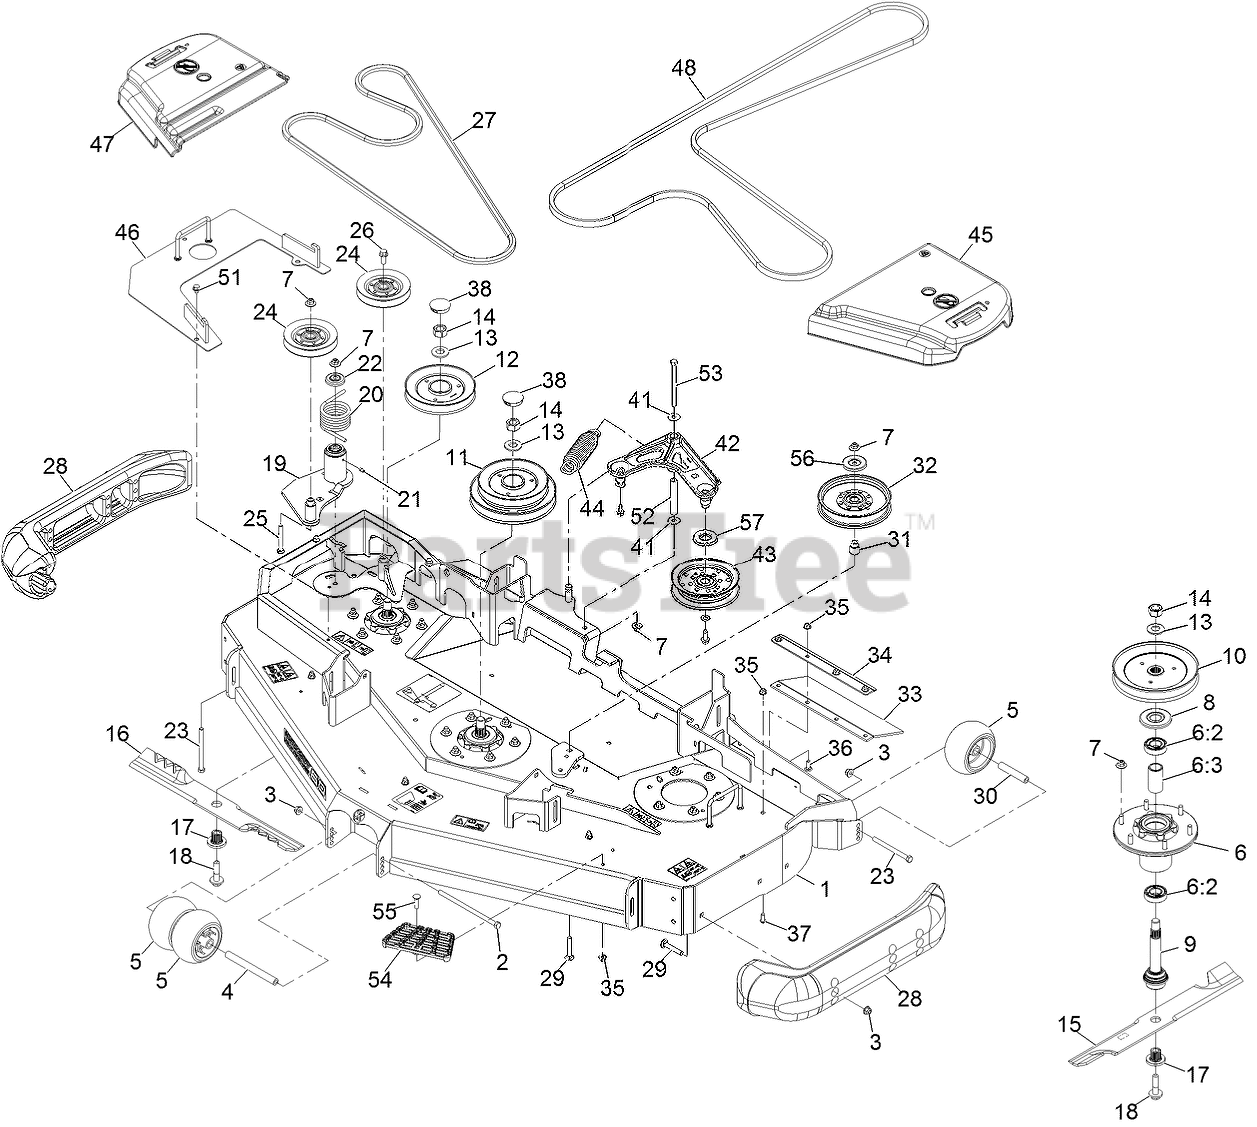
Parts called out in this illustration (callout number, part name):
1	ASM-DECK W/DECALS 60RD
2	SCREW-HH
3	NUT-HF, NI
4	SPACER-WHEEL
5	ROLLER-SCALP, ANTI
6	ASM-CUTTER HSG WITH BEARINGS
6:2	BEARING-BALL
6:3	SPACER-BEARING
7	Nut-Nyloc 3/8-16 Flg
8	GUARD,BEARING TOP .989
9	ASM-SPINDLE AND SEAL
10	SHEAVE,BLADE DRIVE 7.25
11	SHEAVE, DOUBLE 60RD
12	SHEAVE-RD REV DRIVE SERIES 4
14	NUT-HEX
15	Blade-Extreme 2, 20.50"
16	Blade-Low Lift 20.5, Rd60
16	Blade-Extreme 2-20.50, Rd60
17	BUSHING,SPLINED
18	SCREW,SEMS 1/2-20 X 2.19
19	IDLER ASM
20	SPRING-TORSION
21	FITTING-GREASE
22	GUARD-TOP
23	SCREW-HH
25	SCREW-HH
26	SCREW-HHF
27	BELT
28	SKID-BUMPER, DECK
29	Bolt-Carriage 3/8-16 X 2 1/4
30	TUBE-SPANNER
31	BUSHING-IDLER
32	IDLER-PULLEY, FLAT 6.00X1.00
33	GUARD-TIRE
34	SUPPORT-OUTER FLAP
35	NUT-HF, NI
36	SCREW-CARR
37	SCREW-HSBH
38	PLUG,BLACK NYLON 1.75
42	IDLER ARM ASM
43	IDLER-PULLEY, FLAT
44	SPRING-EXTENSION
45	COVER-BELT, LH
46	COVER-DRIVE, REVERSE
47	COVER-BELT, RH
48	BELT-V
52	BUSHING
53	SCREW-HH
54	STEP-DECK
55	Bolt-Carriage 5/16-18 X 1 1/4
56	SHIELD-DUST
57	SHIELD-GUARD, DUST
